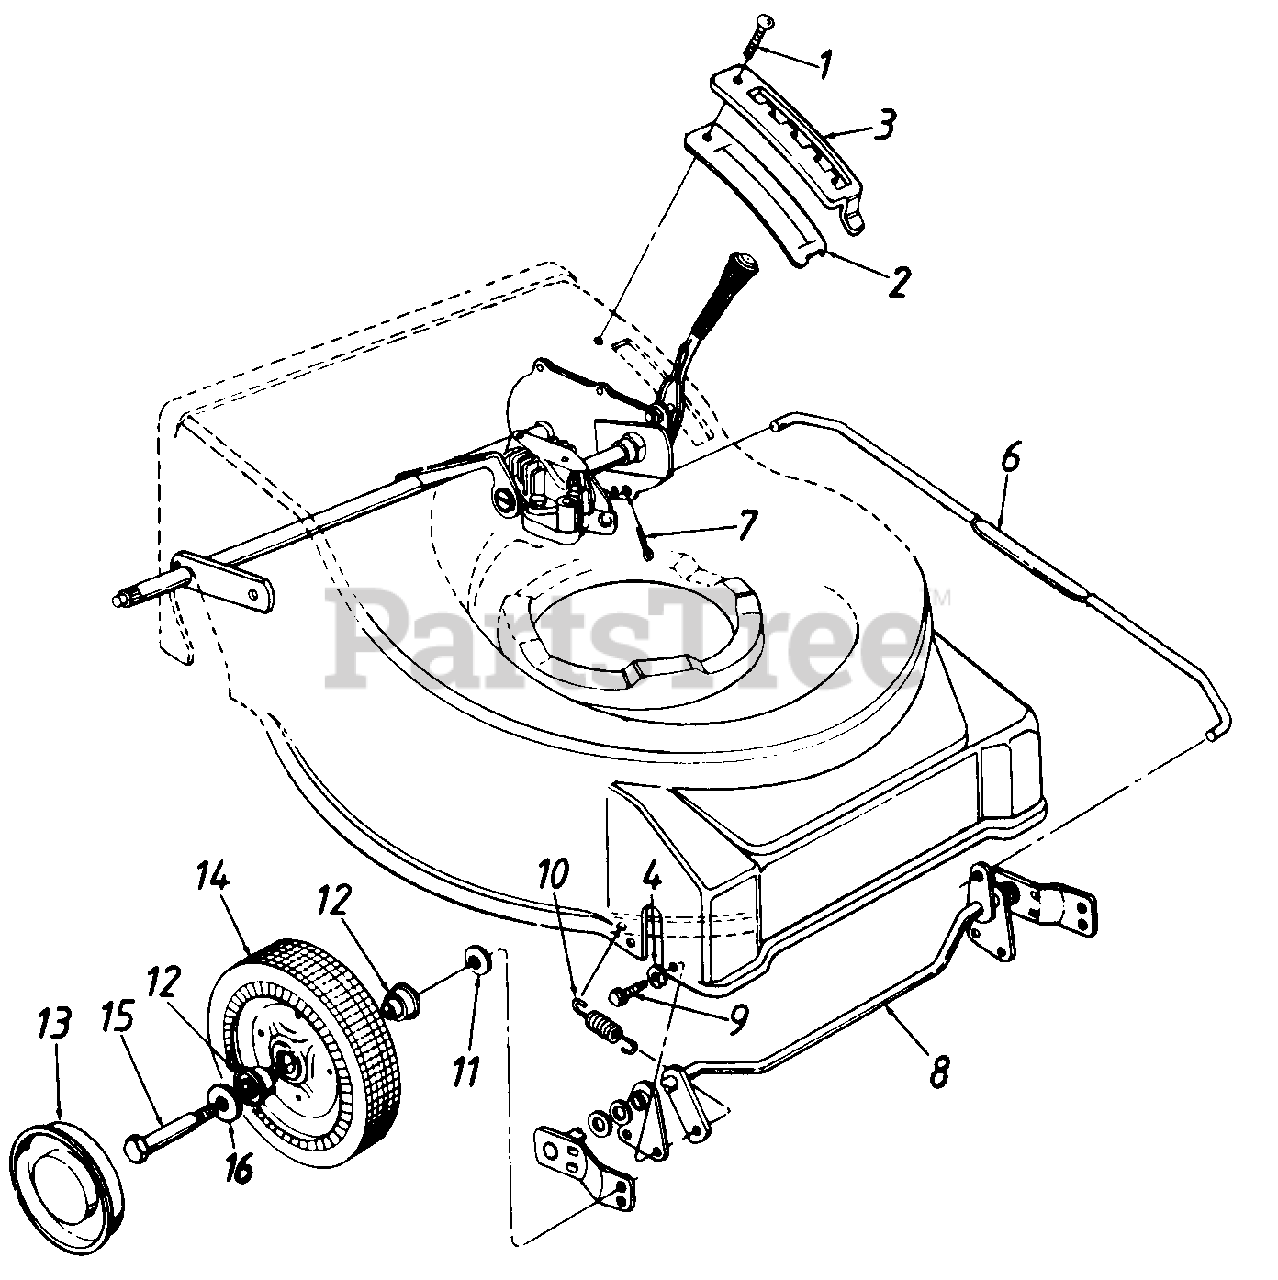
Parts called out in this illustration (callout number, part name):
1	Torx Mach. AB-Tap Scr. 1/4 X .62" Lg.*
2	Height Adjustment Support
3	Height Adjustment Plate
4	L-Wash. 1/4" I.D.*
6	Height Adj. Connecting Rod
7	Cotter Pin 3/32" Dia.
9	Hex L-Wash. Hd. AB-Tap Scr. 1/4 X .88" Lg.
10	Extension Spring 2.39" Lg.
11	Bell-Wash. .380" I.D. x .88"
12	Flange Ball Bearing 1/2" I.D.
13	Hub Cap
14	Wheel Ass'y. Comp.-Front
15	Shld. Bolt .498" Dia. x 1.45
16	Wave Wash. .53" I.D. x .78"
